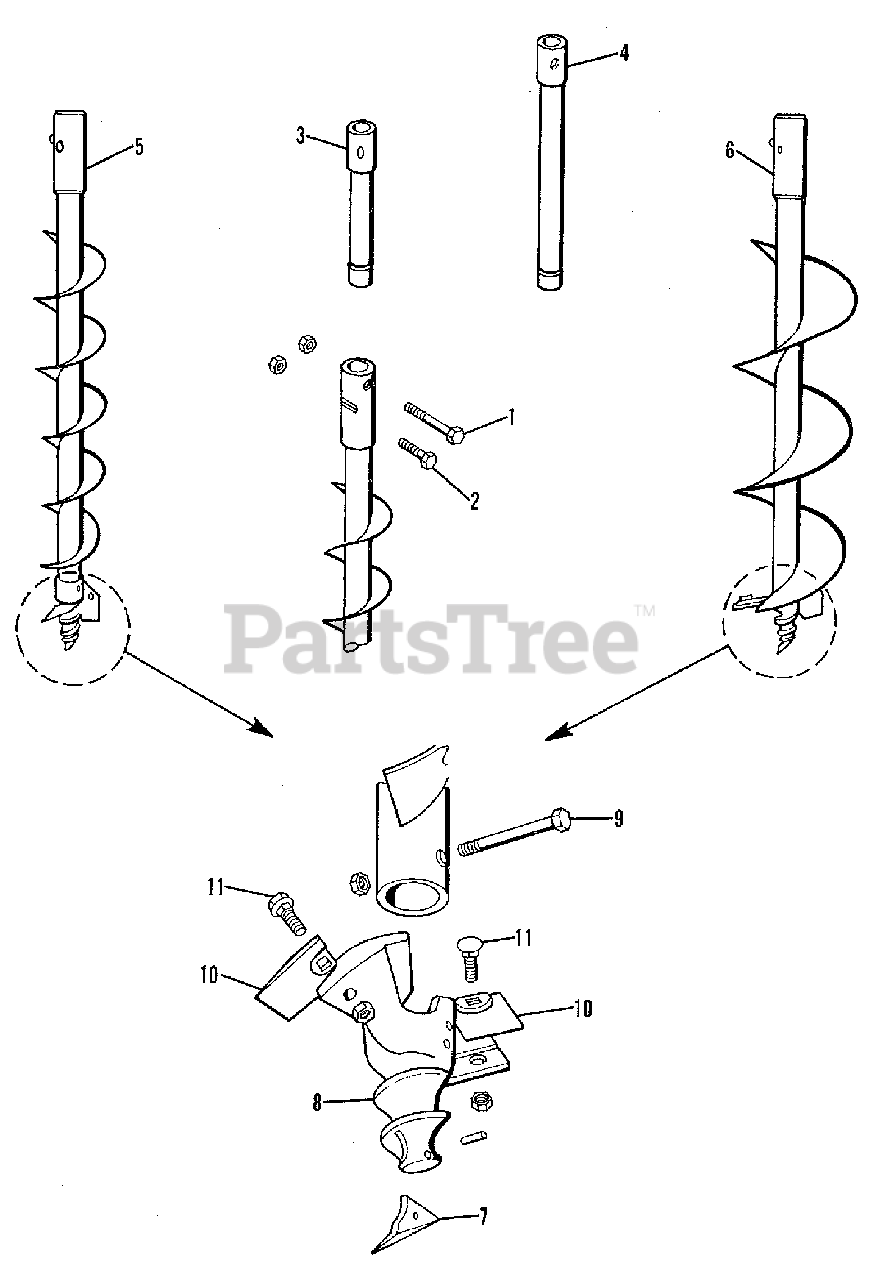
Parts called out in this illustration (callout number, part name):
1	BOLT, Shear
1	NUT, Lock, 7/16NC
2	BOLT, Retaining
2	NUT, Lock, 3/8NC
3	EXTENSION (8" Long)
4	EXTENSION (14" Long)
5	AUGER ASSEMBLY, Complete (6")
5	AUGER ASSEMBLY, Complete (9")
6	AUGER ASSEMBLY, Complete (12")
7	POINT, Cutter Head
8	HEAD, Cutter (For 6" Auger)
8	HEAD, Cutter (For 9" Auger)
8	HEAD, Cutter (For 12" Auger)
9	BOLT, Cutter Head & Auger
9	NUT, Lock, 3/8NC
10	BLADE, Cutting
11	BOLT, Blade & Cutter Head
11	NUT, Lock, 1/2NC
